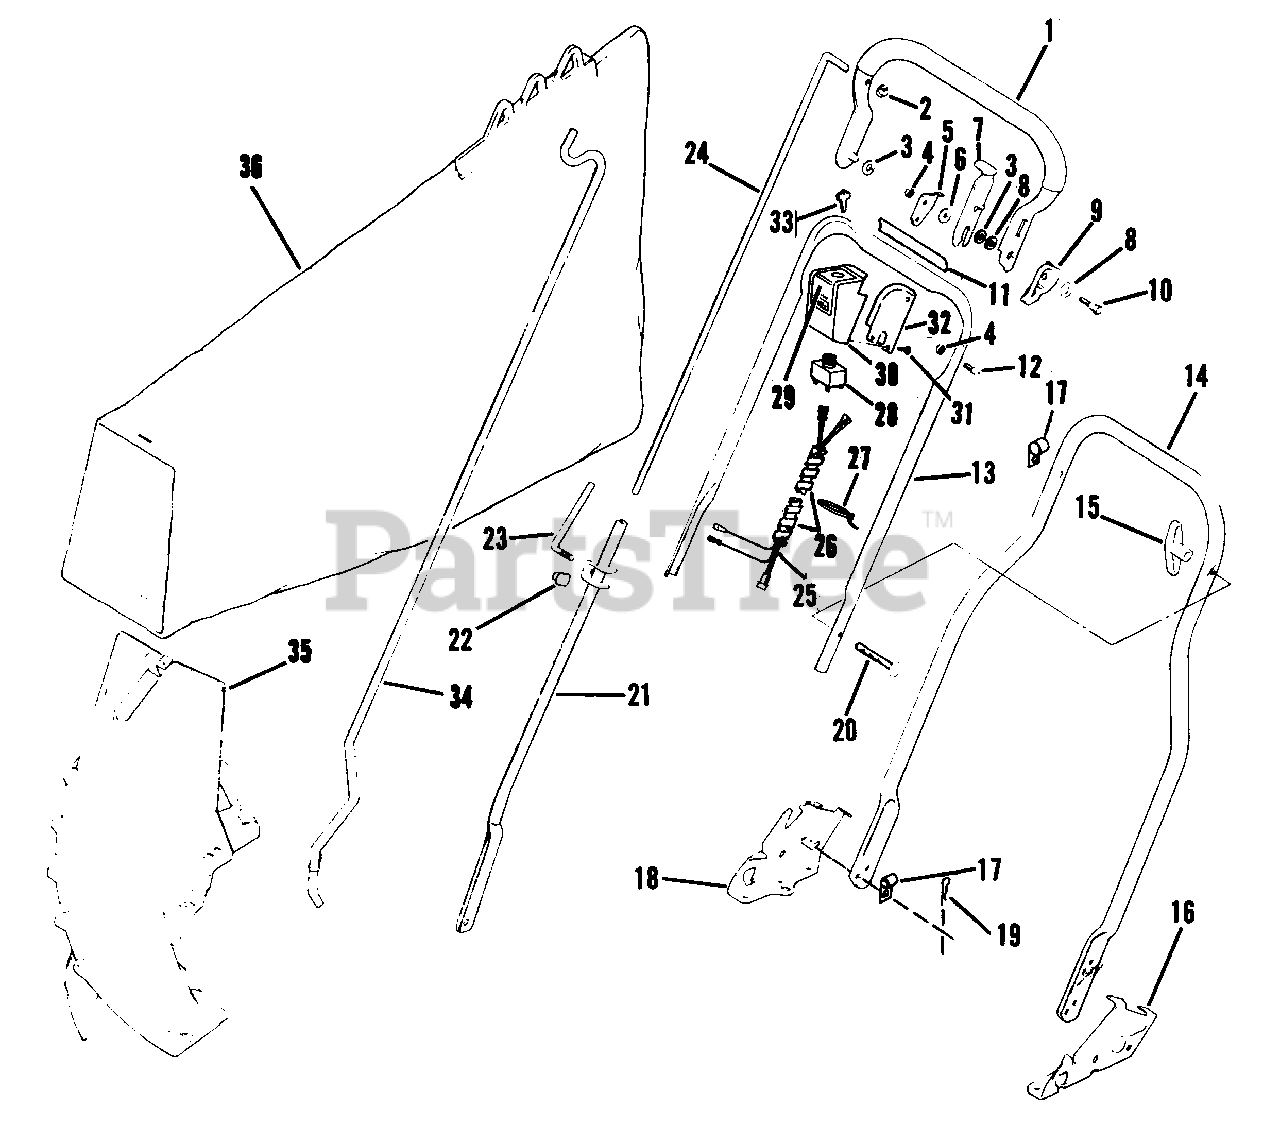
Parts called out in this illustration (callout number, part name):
1	Handle & Grip Assembly
2	Palnut
3	Washer
4	Nut-Lock
5	Stop-Handle
6	Washer
7	Lever-Lockout
8	Washer
9	Guard-Lever
10	Bolt-Shoulder
11	Decal
12	Screw-Stop
13	Handle-Center
14	Handle Section-Bottom
15	Knob
16	Bracket-Handle L.H.
17	Clamp
18	Bracket-Handle R.H.
19	Hair Pin
20	Screw Bolt
21	Control Lever Assembly
22	Nut
23	Screw
24	Control Rod
25	Wire Harness Assembly Switch
26	Spiral Tubing
27	Cable Tie
28	Key Switch
29	Decal-Switch
30	Housing-Switch
31	Screw
32	Retaining Plate-Switch Housing
33	Keys-Switch
34	Rod-Grass Bag
35	Chute Assembly
36	Bag Assembly
